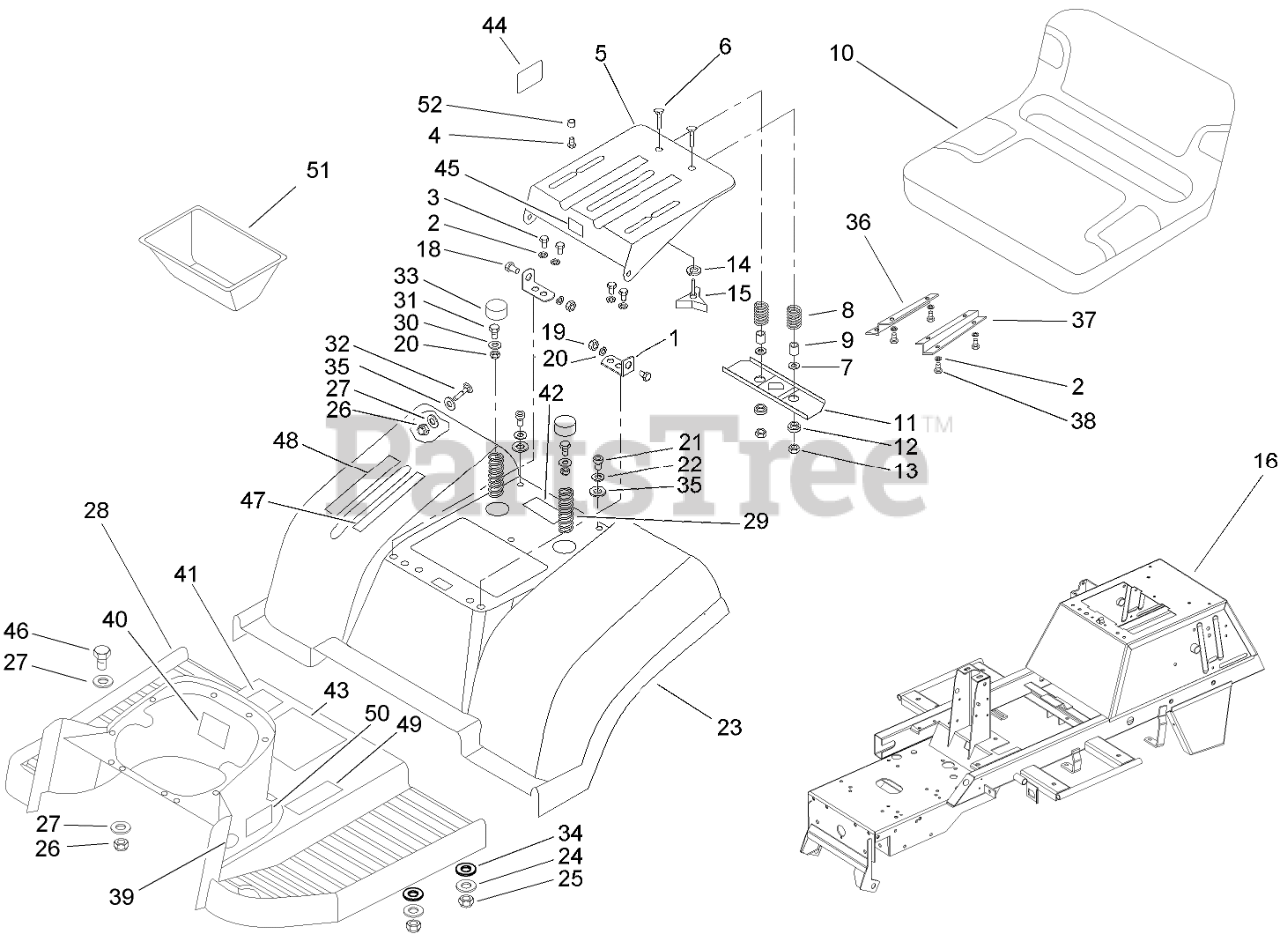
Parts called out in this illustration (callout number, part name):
1	BRACKET-SUPPORT, SEAT
2	WASHER-LOCK, SPRING
3	SCREW-HH
4	SCREW-HH
5	SUPPORT-SEAT
6	BOLT-CARRIAGE
7	WASHER-FLAT
8	SPRING-SEAT
9	SPACER-SPLIT
10	SEAT ASM
11	BRACKET
12	BUSHING
13	NUT-LOCK
14	WASHER-SPRING
15	KNOB-ADJUSTMENT
16	CHASSIS-FRAME
18	SCREW-SUPPORT, SEAT
19	WASHER-PLAIN
20	NUT-LOCK, NI
21	SCREW-HSFH
22	WASHER-FINISH
23	Fender
24	WASHER-FLAT
25	NUT-LOCK, NI
26	NUT-LOCK
27	WASHER-FLAT
28	FOOTREST ASM
29	SPRING-SEAT
30	WASHER-PLAIN
31	SCREW-HH
32	BOLT-CARRIAGE
33	CAP-HUB
34	WASHER-RUBBER
35	WASHER-RUBBER
36	BRACKET-SEAT, RH
37	BRACKET-SEAT, LH
38	Screw
39	DECAL-BRAKE, PARKING
40	DECAL-STARTING
41	DECAL-OPERATION, HYDRO
42	DECAL-BAG TO FRAME
43	DECAL-INSTRUCTION
44	DECAL-SWITCH
45	DECAL-DANGER
46	SCREW-HH
47	DECAL-HOC, LH
48	DECAL-HOC, RH
49	DECAL-OPERATION
50	DECAL-TOWER
51	Box-Battery
52	SHIM-SEAT
